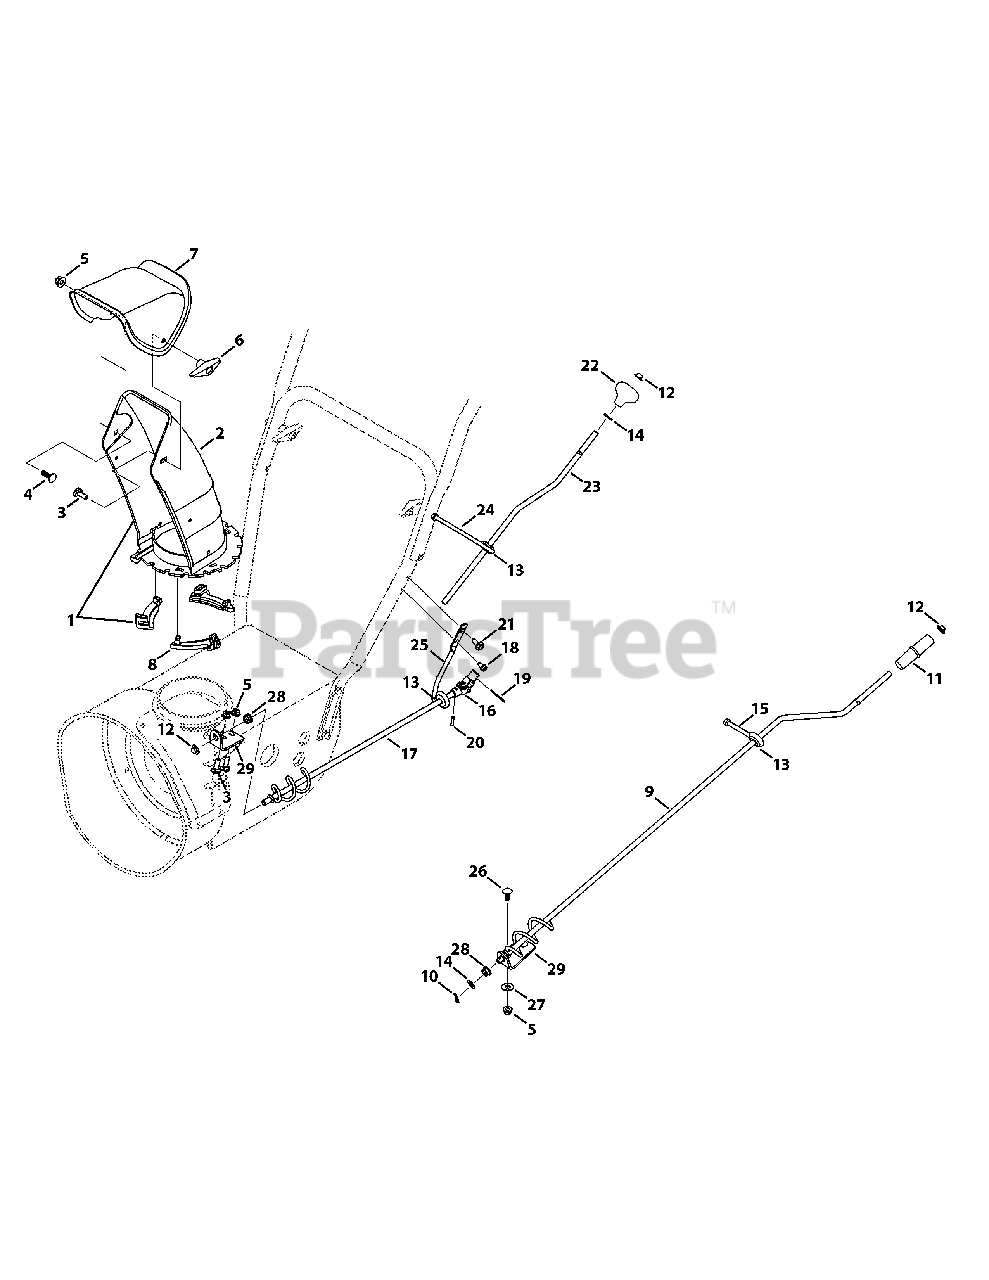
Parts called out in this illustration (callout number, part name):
1	Lower Chute Assembly
2	Lower Chute
3	Carriage Bolt, 5/16-18 x 1.00
4	Carriage Bolt, 5/16-18 x .750
5	Flange Lock Nut, 5/16-18
6	Wing Knob
7	Upper Chute
8	Flange Keeper
9	Chute Crank
10	Cotter Pin, .072 x 1.13
11	Crank Knob
12	Push Cap, 3/8
13	Rubber Grommet
14	Flat Washer, .375 x .738 x .063
15	Eye Bolt
16	Joint Assembly
17	Chute Crank
18	Taptite Screw, 1/4-20 x .500
19	Cotter Pin, .08 x 1.42
20	Pin, .156 x .875
21	Taptite Screw, 5/16-18 x 2.25
22	Shift Knob
24	Chute Rod Eye Bolt
25	Lower Chute Rod
26	Carriage Screw, 5/16-18 x 1.00
27	Flat Washer, .349 x .879 x .063
28	Plastic Bushing, .380 ID
29	Chute Crank Bracket
